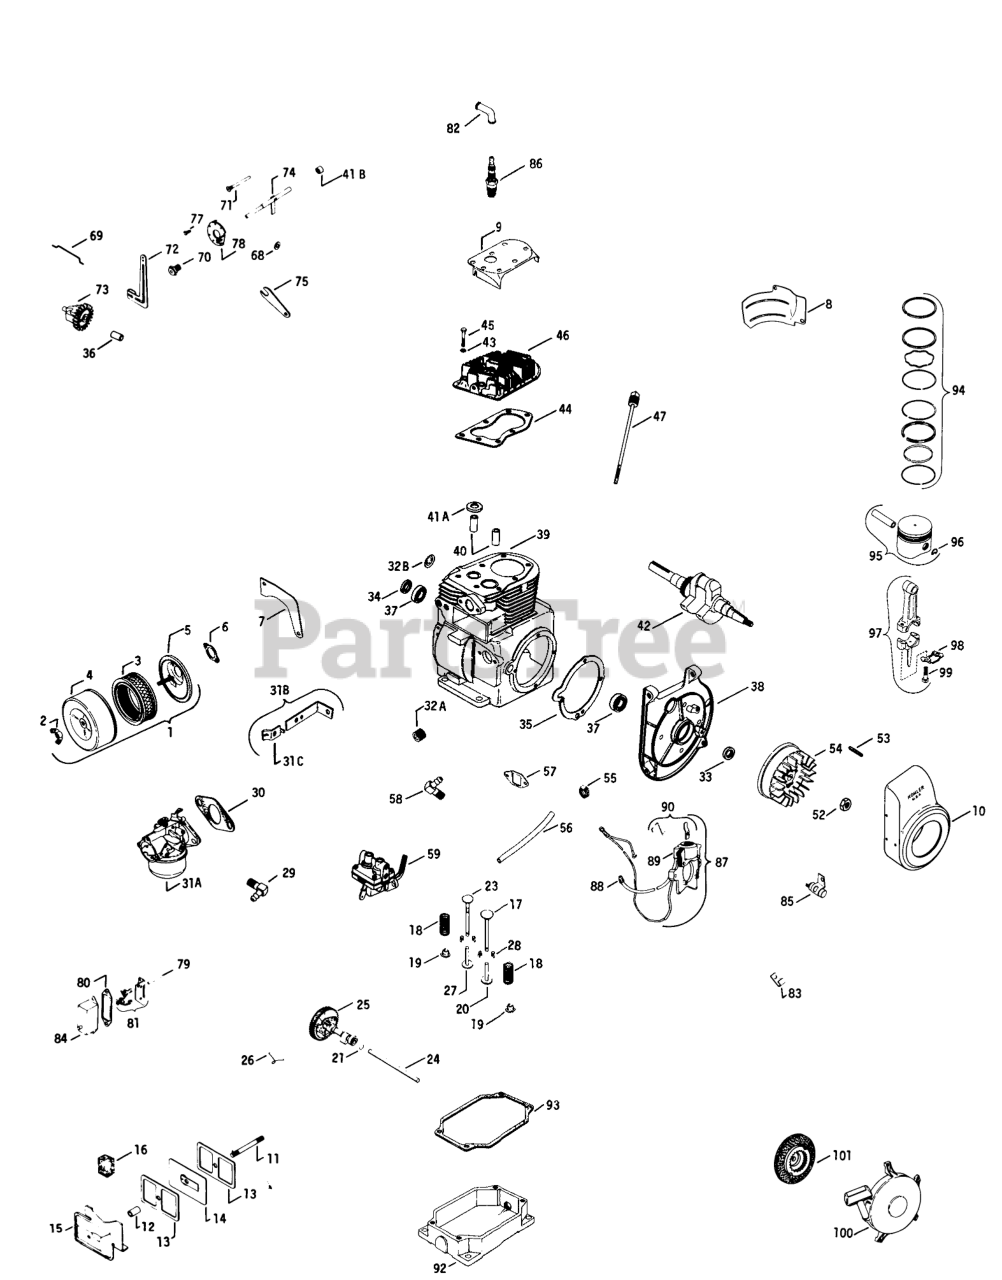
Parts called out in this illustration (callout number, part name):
1	Cleaner, air-assembly
2	Nut-Wing
3	Element, Air Cleaner
4	Cover, air cleaner
5	Base Air Cleaner
6	Gasket
7	Baffle side air
8	Baffle cylinder
9	Baffle, Head
10	Housing, blower
11	Stud valve cover
12	Seal
13	Gasket-Valve Cover
14	Breather
15	Cover, Valve
16	Filter
17	Valve-Intake
18	Spring, Valve
19	Retainer-Spring
20	Tappet, Valve
21	Spacer camshaft .005
21	Spacer, Camshaft.010
23	Valve, exhaust
24	Pin, Camshaft
25	Kit, camshaft
27	Tappet, exhaust valve
28	Keeper, spring
29	Elbow
30	Gasket-Carburetor
31A	Carburetor-Assembly
31A	Repairkit
31B	Bracket, choke
31C	Clip
32A	Plug
32B	Plug
33	Seal Front Oil
34	Seal Rear Oil
35	Gasket
36	Pin-Dowel
37	Ball Bearing
38	Plate, bearing
39	Block, cylinder-assembly (Use B-234989 Miniblock)
40	Guide-Valve
41A	Insert
41B	Bearing
42	Crankshaft
43	Washer
44	Gasket, head
45	Screw, H.C. 5/16-18 x 1-1/2
46	Head, Cylinder
47	Dipstick
52	Nut
53	Key
54	Flywheel (Use 41025 11 after serial no. 6366215)
55	Clamp
56	Line, Fuel
57	Gasket, fuel pump
58	Elbow
59	Pump, fuel
68	Washer
69	Link-Governor
70	Bushing Governor
71	Pin-GovemorStop
72	Lever, Governor
73	Gear, Governor
74	Shaft-Governor Cross
75	Bracket, speed control
77	Pin
78	Disc, regulating
79	Rod, Breaker
80	Gasket, Cover
81	Breaker
82	Boot, Spark Plug
83	Clip
84	Cover breaker
85	Condenser
86	Spark plug
87	Stator-assembly
88	Cable, Hi-Tension
89	Kit, coil
90	Kit, Coil Clip
92	Pan, oil
93	Gasket, pan
94	Ring Set Std.
94	Ring Set .010
94	Ring Set.020
94	Ring Set .030
95	Piston-assembly (Std.)(Includes pin & retainers)
95	Piston-assembly (.003)(Includes pin & retainers)
95	Piston-assembly (.010)(Includes pin & retainers)
95	Piston-assembly (.020)(Includes pin & retainers)
95	Piston-assembly (.030)(Includes pin & retainers)
96	Retainer, Pin
97	Rod, Connecting Std.
97	Rod, Connecting
98	Lock, Conn. Rod
99	90A9-5/66734 SENSAT
100	Starter, recoil-assem.
101	Cup, drive w/screen (Replaced by 41 071 02--41 071 02 must be used after serial no. 6366215)
101	Gasket Set
101	Miniblock
101	Service Engine
